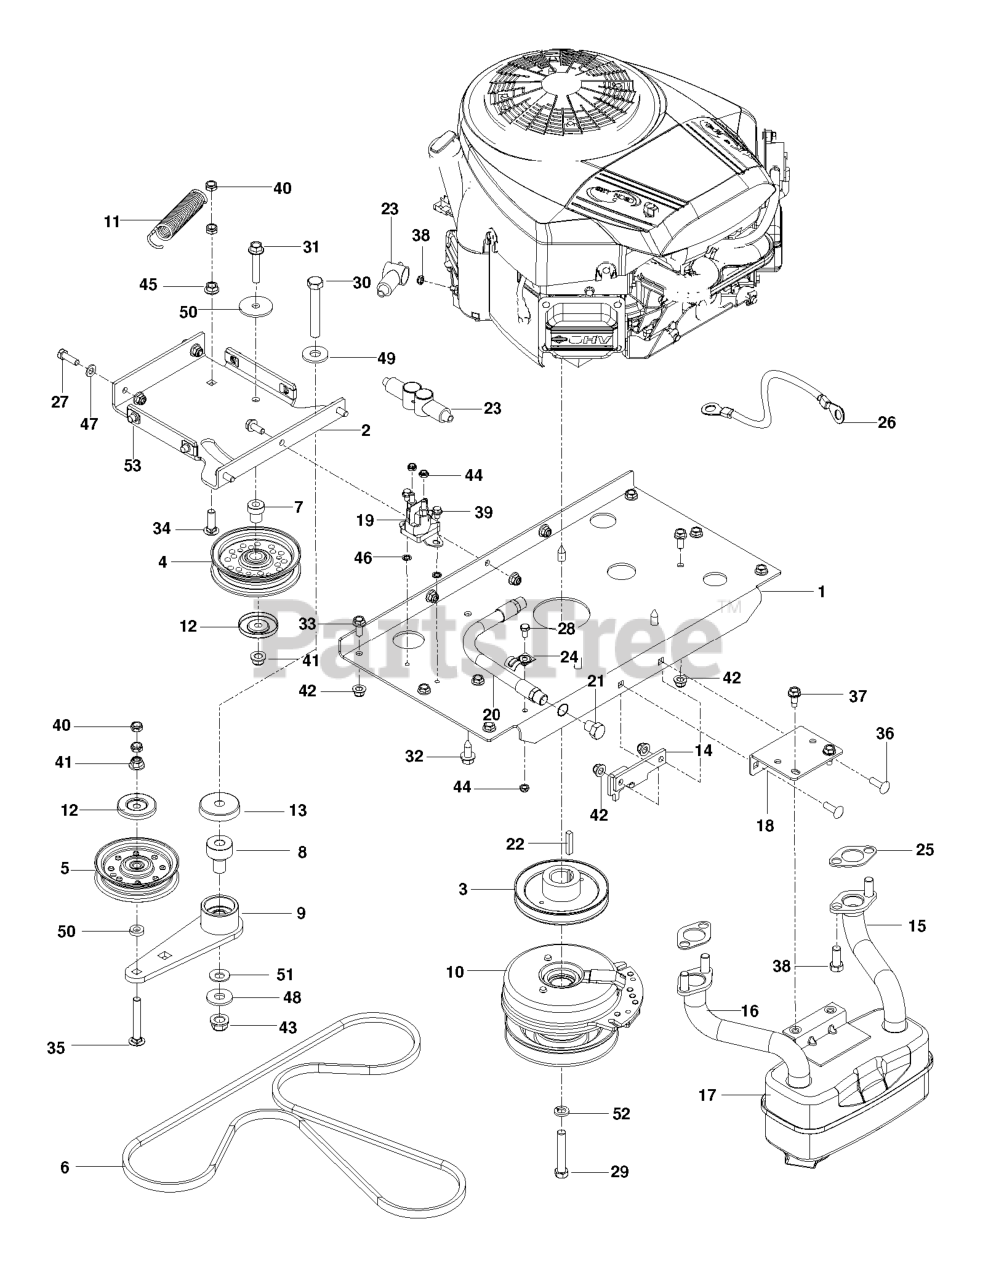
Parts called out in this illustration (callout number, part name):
1	PLATE, ENGINE W/DECALS
2	PLATE, IDLER, BLK
3	PULLEY, V, 1.125 BORE
4	IDLER PULLEY
5	FLAT IDLER PULLEY
6	BELT, HYDRO, 3400
7	PIVOT, IDLER
8	PIVOT, BEARING
9	ARM, IDLER, STEEL, W/BGS
10	CLUTCH 200 FT LB
11	SPRING, PUMP
12	DUST SHIELD
13	SHIELD, DUST
14	STOP, CLUTCH, BLACK
15	EXHAUST.TUBE.RH.B&S.TWIN.INTEK
16	EXHAUST.TUBE.LH.BS/TWIN
17	MUFFLER ASM TWIN
18	BRKT, MUFFLER, BLK
20	HOSE.ASSEMBLY.OIL.DRAIN
21	PLUG OIL DRAIN
22	KEY, 1/4 SQ X 1 1/4
25	GASKET.MUFFLER
26	CABLE POSITIVE
27	HCS 5/16C X 1
28	HCS 1/4-20.
29	CLUTCH BOLT7/16-20X2.5 GR596HR
30	HCS 1/2C X 3 1/4
31	HHFS 3/8-16 X 2.0 GD 5
32	HHFS 3/8-16 X 1.0 THD FORMING
33	HHFS 5/16-18 X 3/4
34	RHSNB 3/8-16 X 1-1/4
35	RHSNB 3/8-16 X 2.75
36	RHSSNB 5/16C X 1.0
37	BOLT 5/16-18 X 3/4
38	SCREW.SOCKET.HEAD.5/16-18
39	HWST 1/4C X 3/8
40	NUT HEX 3/8-16 NYLON, THIN
41	NUT 3/8-16 HEX FLG NYLOC ZD
42	5/16-18 NYLOC FLANGE NUT
43	NUT, 1/2-13 HEX FLG NYLOC ZD
44	JAM NUT 1/4C (2 2 PW01)
45	NUT 3/8C WHIZ
46	WASHER 1/4 INT TOOTH
47	FLAT WASHER 5/16 SAE
48	WASH USS FLAT 1/2
49	WASHER 3/8 X 3/4 X .187 TK
50	WASHER, 3/8 SPEC
51	CONTACT BELLSPR 1/2
52	WASHER 7/16 LOCK
53	U-CLIP 5/16-18 NUT RETAINER
